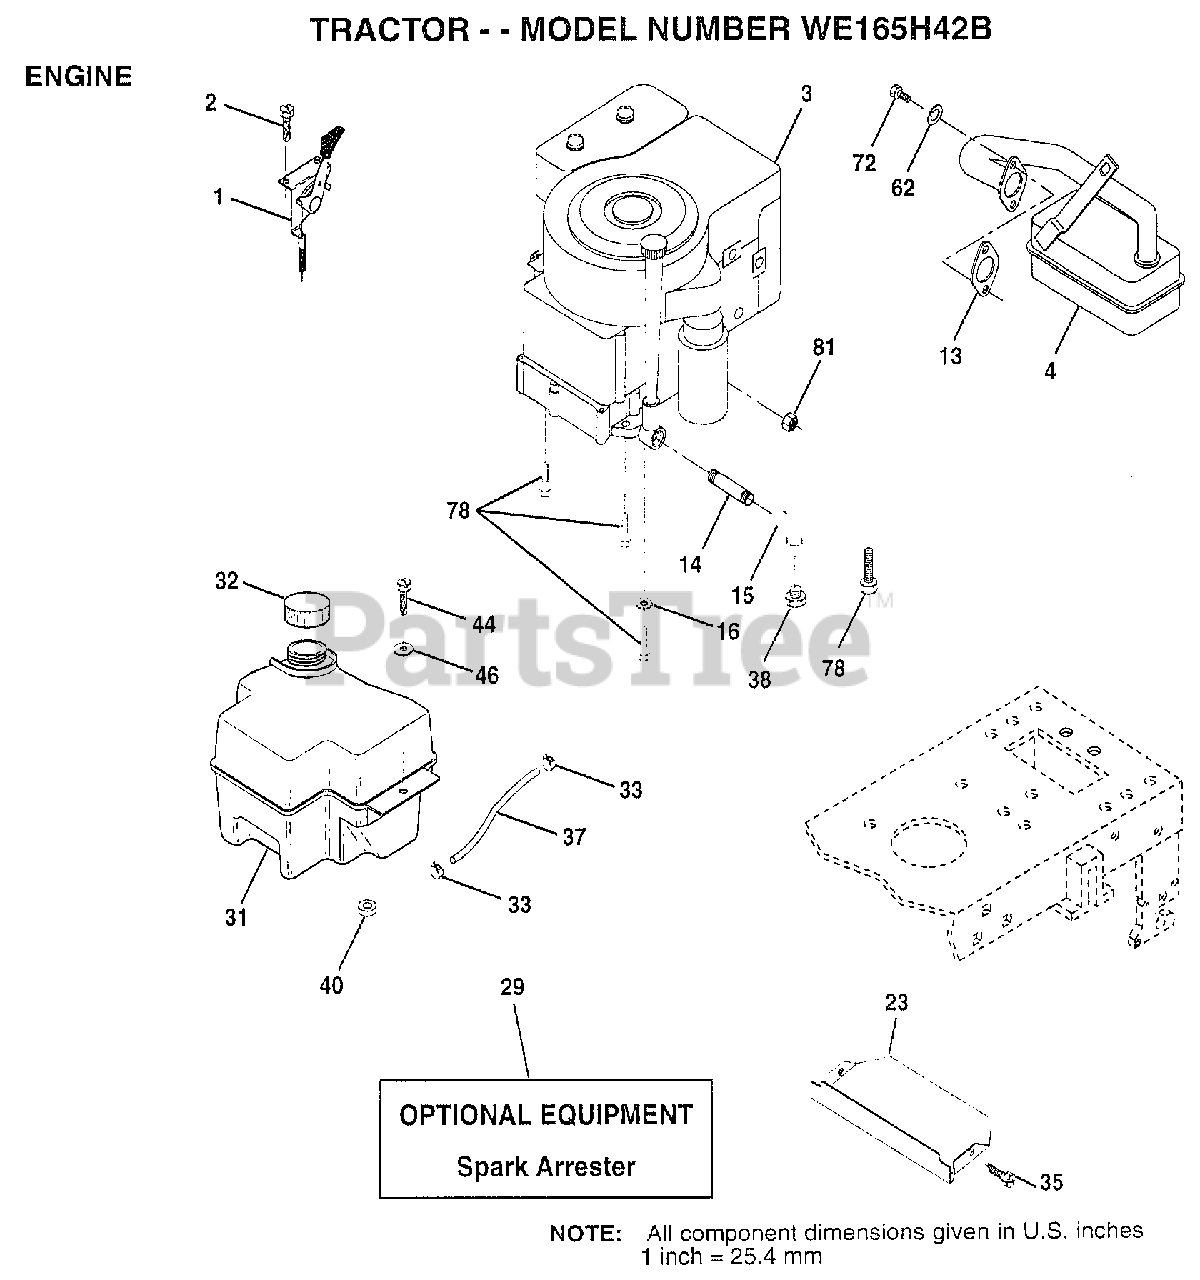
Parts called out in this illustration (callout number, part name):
1	CONTROL THROTTLE
2	SCREW LT
4	MUFFLER
13	GASKET ENG 1 313 LD TIN PLATED
14	PIPE NIPPLE
15	ELBOW
16	LOCKWASHER
23	SHIELD.BRN/DBR.GD
31	TANK.FUEL.FRONT.
32	CAP ASM FUEL
33	HOSE CLAMP
35	SCREW
37	LINE FUEL
44	SCREW HEX CRT
46	WASHER
62	LOCKWASHER
72	SCREW
78	SCREW
81	NUT
